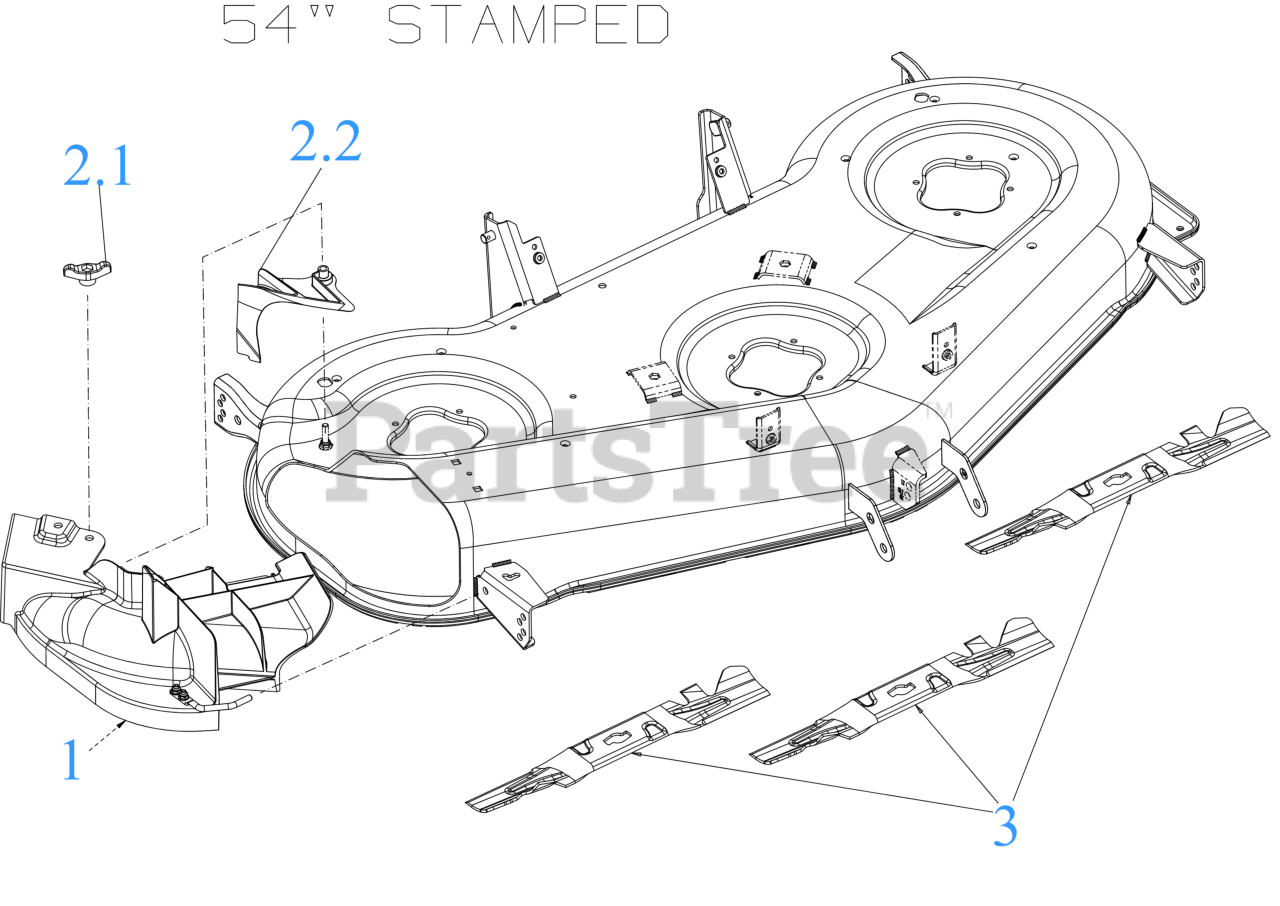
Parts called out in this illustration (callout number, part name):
1	MULCH PLUG ASSEMBLY
1	FLANGE LOCK NUT
1	MULCH PLUG MOUTING ROD
1	SCREW 1/4-20X.75 GR5
1	FLAT WASHER
2.1	WING KNOB 5/16-18
2.2	CHUTE ADAPTER
3	18.611" XTREME BLADE (2IN1) (S SHAPE CENTER HOLE)
